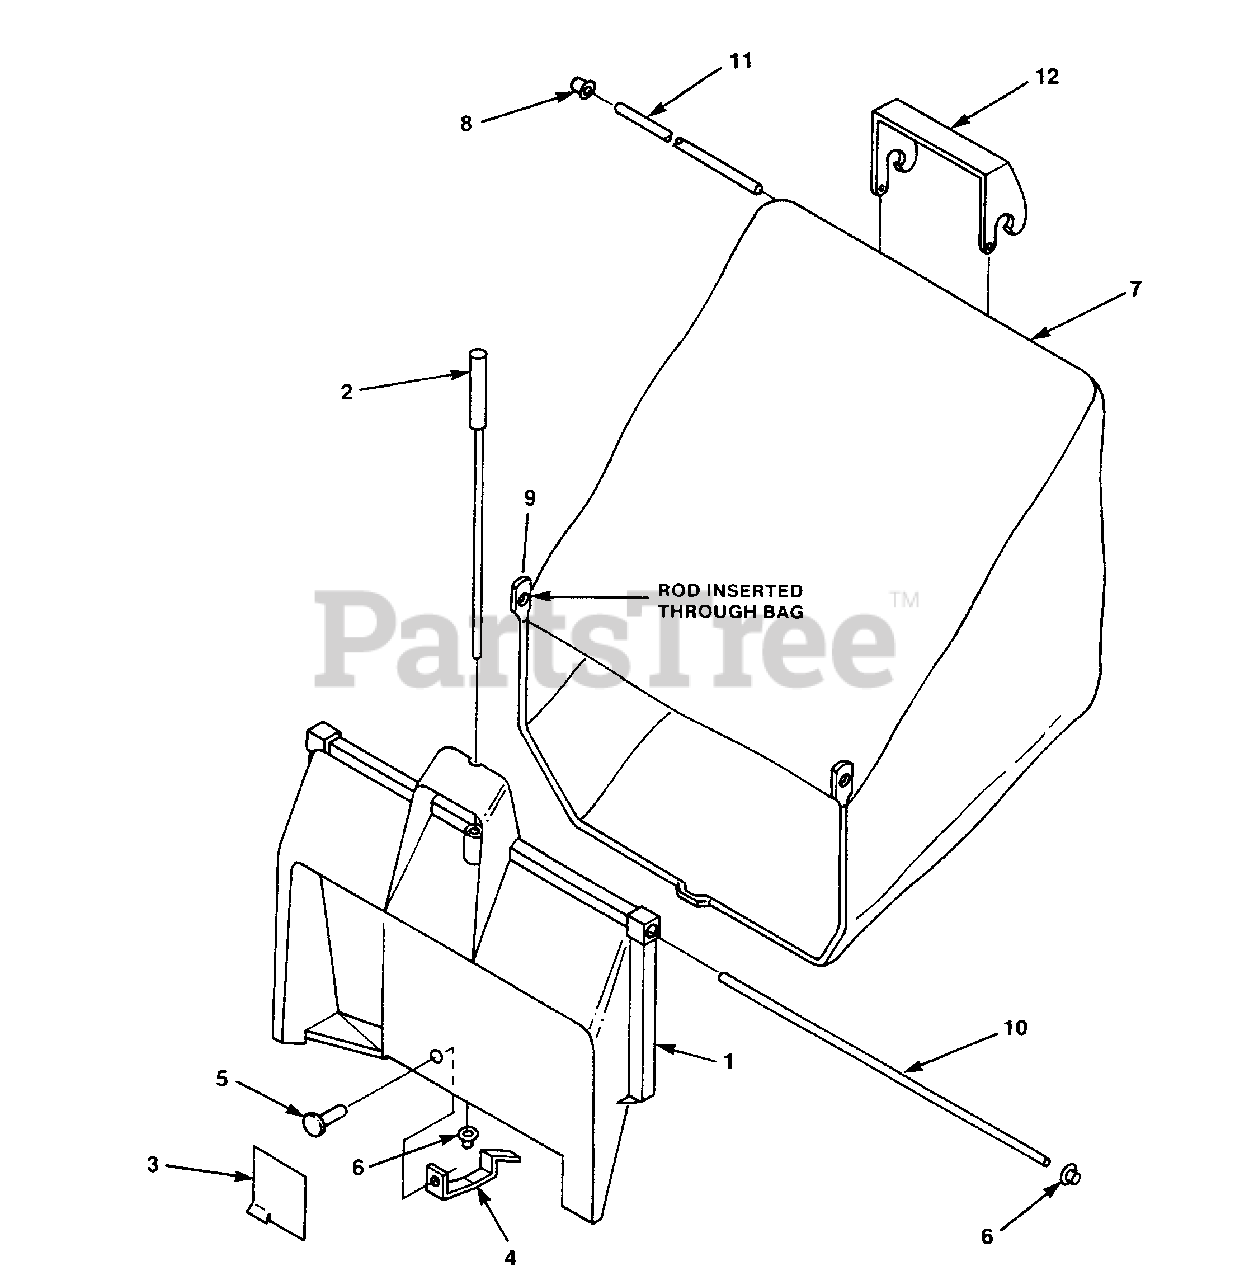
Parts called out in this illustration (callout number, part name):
1	ADAPTOR- Bag
2	ROD- Latch release
3	DEFLECTOR
5	RIVET- Pop 5/32 x 3/8
7	CATCHER- Grass
9	ROD- Bag Support
10	ROD- Bag hinge
11	ROD- Upper bag
12	HANDLE- Upper bag
